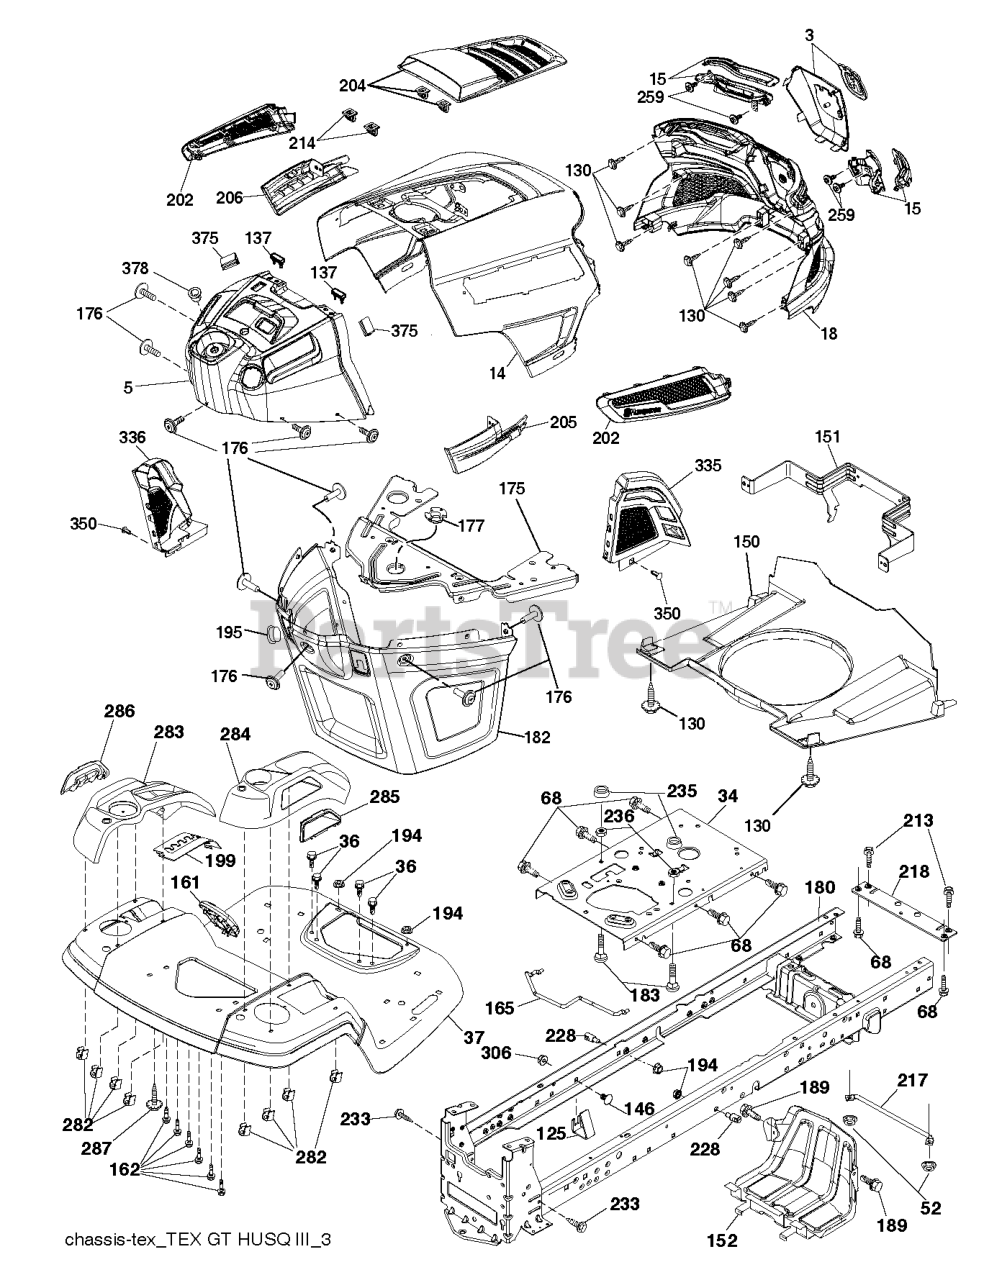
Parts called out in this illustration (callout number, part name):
5	DASH.UPR.GT2.SM.PTO.MC.HR.498
14	HOOD.ASM.HUSQVARNA.GT.TEX.ORAN
15	Service Kit
34	PLATE.ENGINE.WELDED.CHASSIS
36	SCREW 5/16"
37	FENDER.TLT.FS.W/CPH/FW/RSF.668
125	CLIP.FUEL.LINE
137	BUMPER DASH
146	BOLT.RDHD.SHT.SQNK.3/8-16X5/8
150	AIR.DUCT.GTV.BLACK
151	BRACKET.PIVOT.HOOD.GT.HUSQ.II
152	SHIELD.BROWNING.PNT.GT.V2
161	WINDOW.FUEL.LT.HUSQ.TEX.498
165	SUPPORT.TANK.REAR.W/TEX
175	PLATE.PNT.CROSSMEMBER.HUSQ/PRE
176	SCREW.#10-24X5/8.RN.QU
177	BUSHING STEERING
180	CHASSIS
182	DASH.LOWER.COMMON.12V.ADAPTOR
189	SCREW
195	PLUG.HOLE.DASH.LOWER.12V.BLK
199	PLATE.DECK.LIFT.HUSQ.LT
202	Vents
205	SIDE.TRIM.RH.GT.HUSQ.II
206	SIDE.TRIM.LH.GT.HUSQ.II.GRAY
213	SCREW HEXAGON HEAD SCREW 5/16-
214	CLIP.RETAINER.TINNER.
217	ROD.PIVOT.HOOD
218	X-PIECE.HOOD.STOP.NON/
228	STUD.W/"D"ANTI-ROTATION
233	BOLT.SHOULDER
236	NUT.CENTERLOCK.5/16-
282	CLIP.RETAINER.CONSOLE.LT.HUSQ
283	CONCOLE.CNTRL.PDL.HUSQ.LT.498
284	CONSOLE.DECK.LIFT.R.SDFL.HUSQ
285	CONSOLE INSERT RH
286	CONSOLE.INSRT.LH.HUSQ.LT.BLACK
287	SCREW 1/4X20
306	NUT LOCK FLG 3/8-16 UNC
335	COVER.LOWER.DASH.RH.BLACK
336	COVER-LH.LOWER.DASH.GT2.BLACK
350	CLIP.X-MAS.TREE
375	BUMPER CLIP-ON. DASH 1"
378	BUSHING FLANGE; PLASTIC
